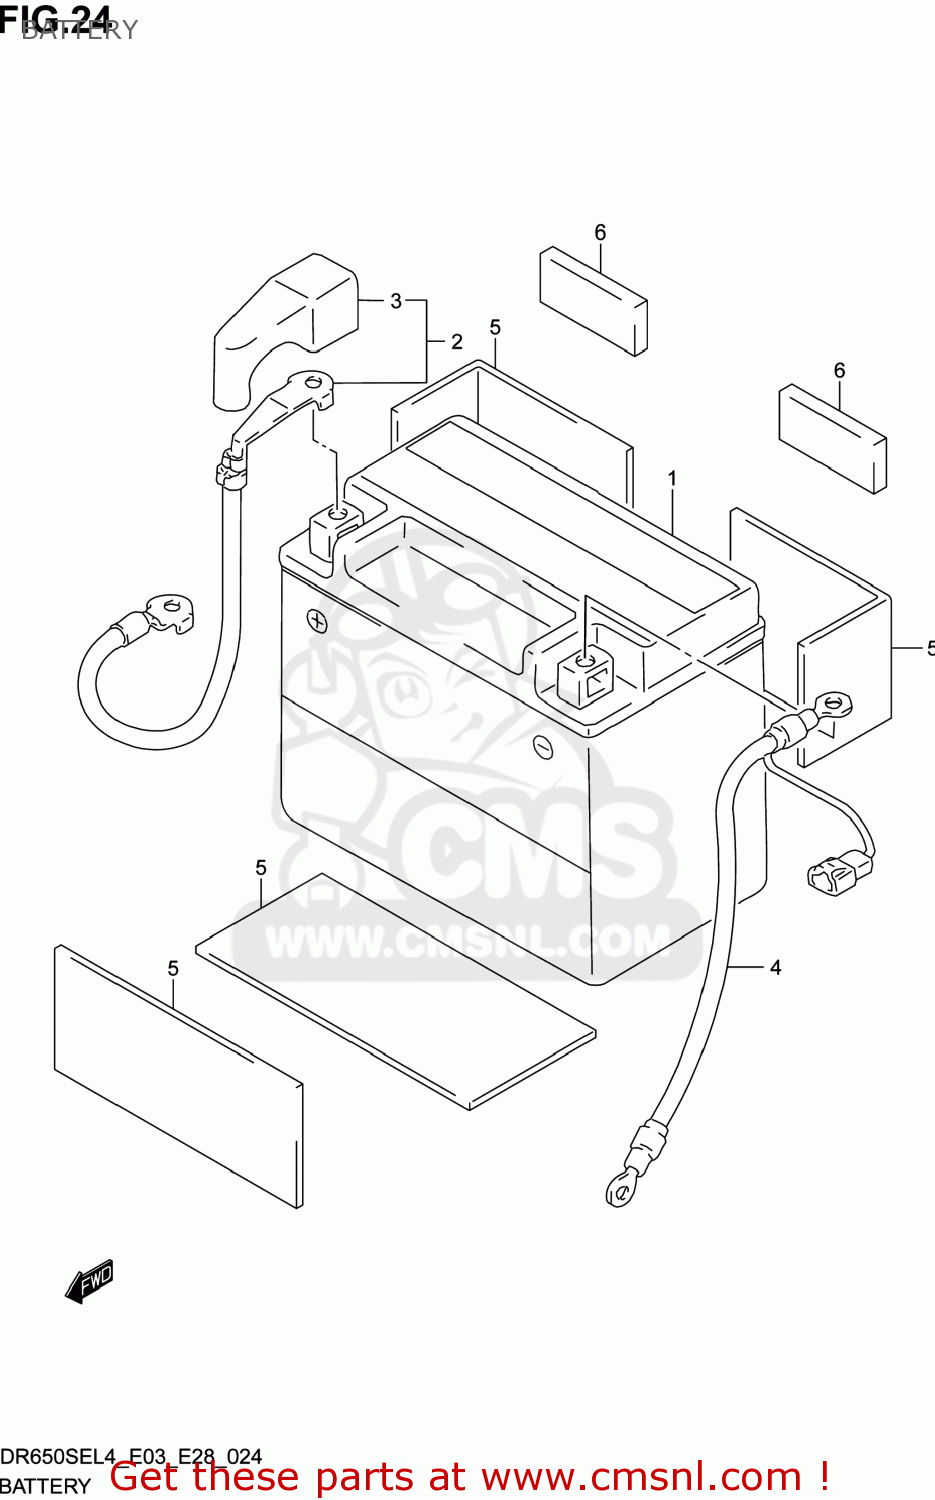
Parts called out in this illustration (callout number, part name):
1	BATTERY ASSY(YTX9-BS,12V8AH)
2	WIRE,BATTERY PLUS
3	CAP,BATTERY PLUS TERMINAL
4	WIRE,BATTERY MINUS
5	PROTECTOR(170X95X3.0)
6	PROTECTOR,BATTERY(70X100X6)
